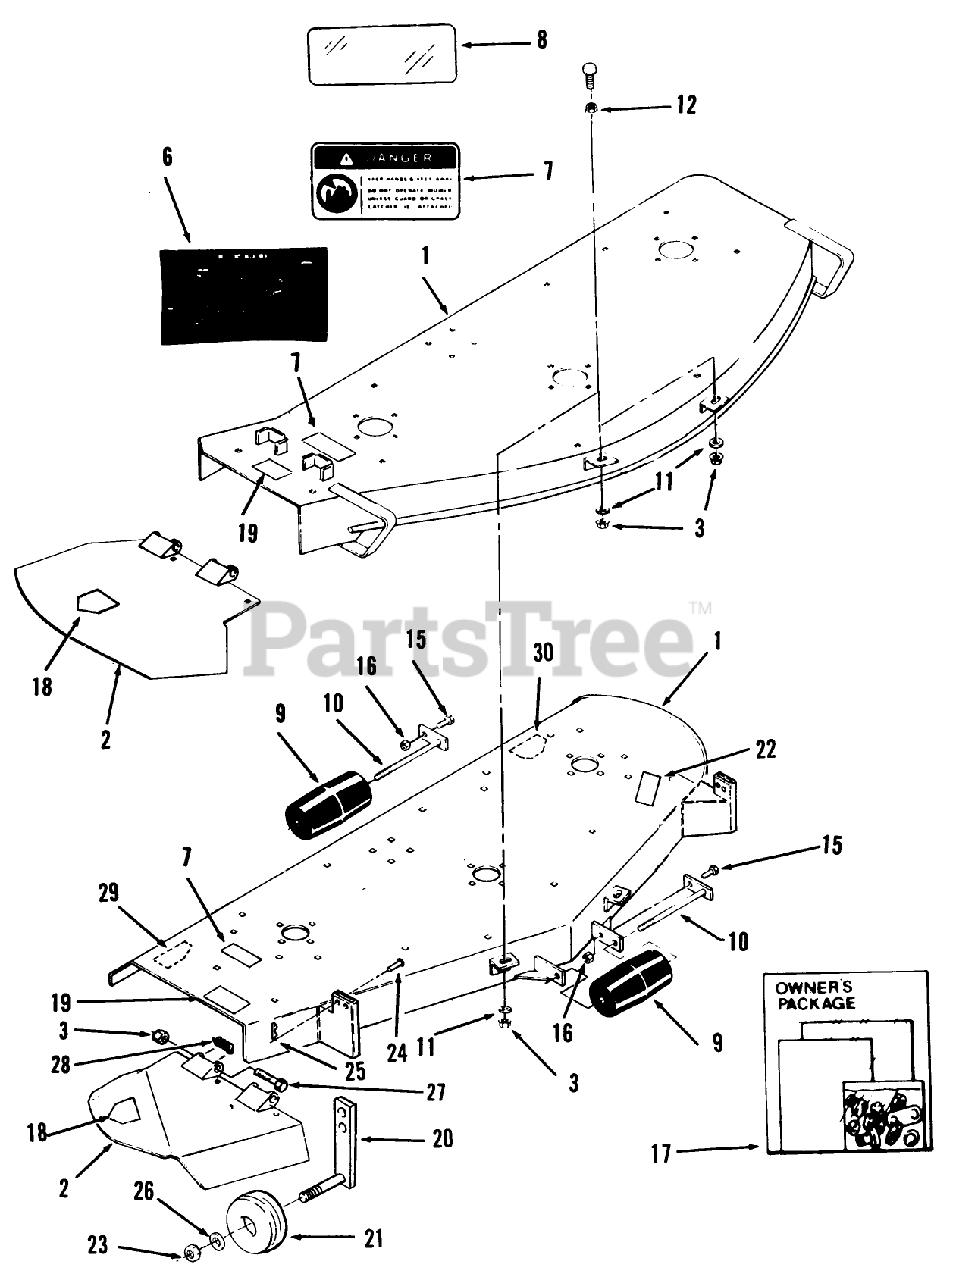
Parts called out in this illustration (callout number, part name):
1	Mower Deck-50" Mower
2	Discharge Chute-50" Mower
3	NUT-LOCK, NI
6	DECAL-BELT INSTAL
7	DECAL-DANGER, THROWN OBJECT
8	DECAL-OVERLAY
9	ROLLER-ANTI SCALP
10	ROLLER-SHAFT
11	WASHER-FLAT
12	NUT-FLANGE
15	BOLT-CARR
16	NUT-LOCK, NI
17	Loose Parts Package-60" Mower
18	DECAL-DANGER
19	DECAL-DANGER
20	GAGE-WHEEL
21	WHEEL-GAGE
22	DECAL - WHEEL ADJUSTMENT
23	NUT-LOCK, NI
24	Pin-Clevis
25	Hairpin
26	WASHER-FLAT
27	SCREW-HH
28	SPRING
29	Wear Plate RH
30	Plate-Wear, L.H.
